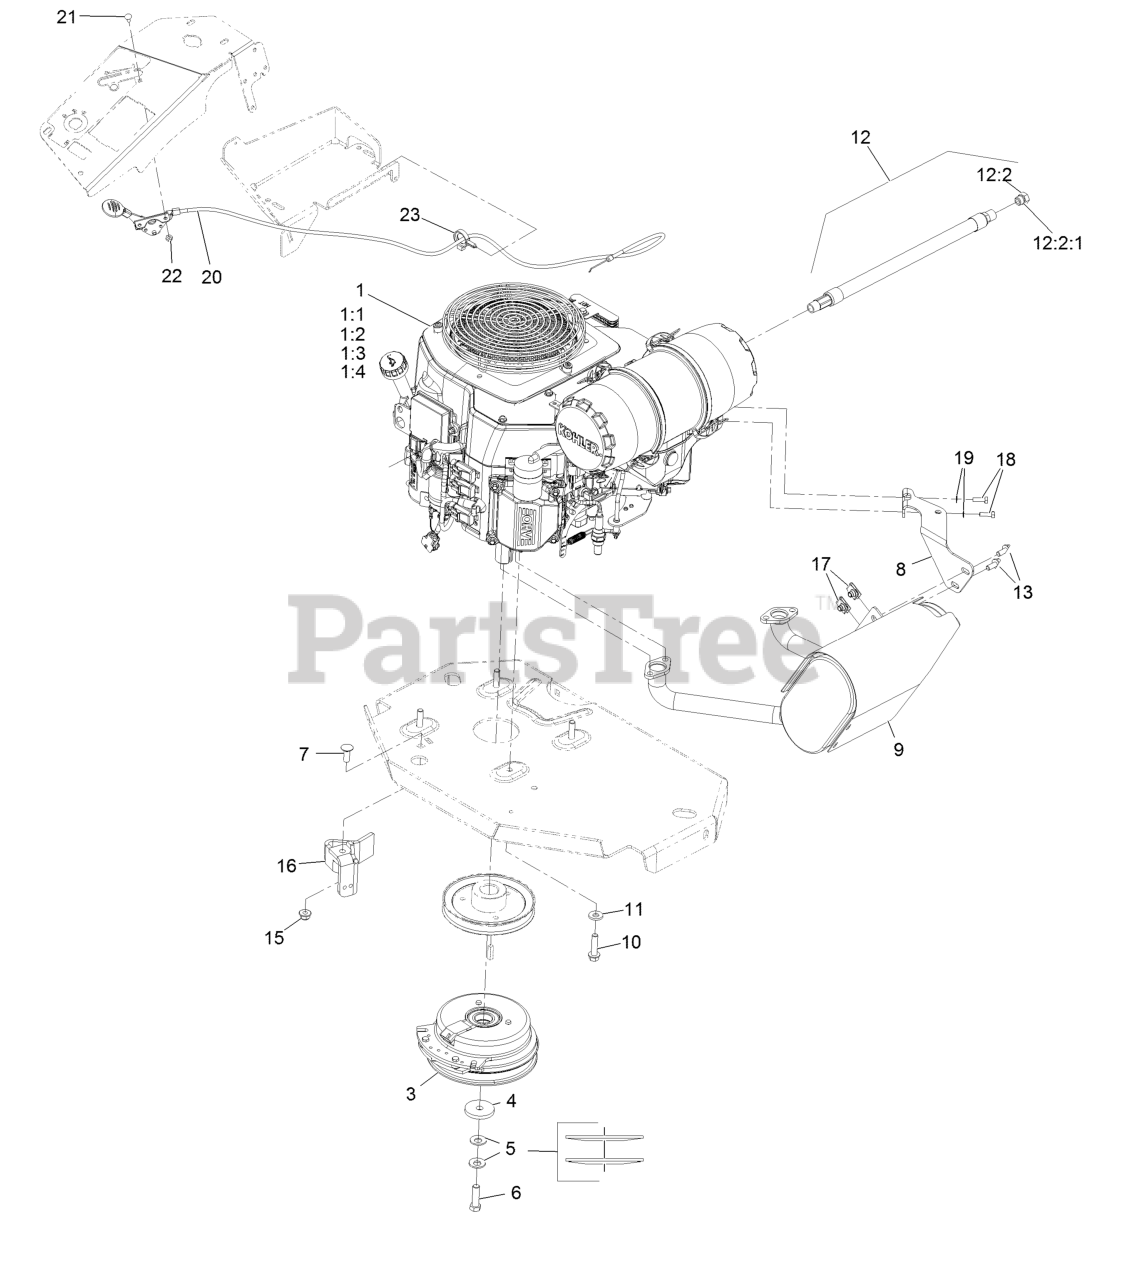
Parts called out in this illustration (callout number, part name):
1:1	Kohler 52 050 02-S Engine Oil Filter
1:2	Kohler 25 083 01-S Engine Air Filter
1:3	Kohler 25 083 04-S Safety Filter
1:4	Kohler 25 050 50-S Propane Fuel Filter
3	Clutch Kit
4	Washer-Clutch
5	Washer-Spring Disc 7/16
6	Screw-HH 7/16-20 X 1 1/2 W/Loctite
7	Bolt-Carriage 3/
8	Muffler Bracket
9	Muffler Kit
10	Screw-HWH 3/8-16 X 1 1/2 Taptite
11	Washer-Spring Disc 3/8
12	Oil Drain Hose ASM
12:2	Plug-W/O-Ring
12:2:1	O-Ring
13	Screw-HH Flg 5/16-18 X 3/4
15	Nut-Nyloc 3/8-16 Flg
16	Clutch-Anchor
18	Screw-HH M6-1 X 20Mm W/Patch
19	Washer-Spring Disc 1/4
20	ASM,Throttle Cable
21	Bolt-Carriage #10-24 X 1/2
22	Nut-Nyloc #10-24
23	Clamp-Hose
